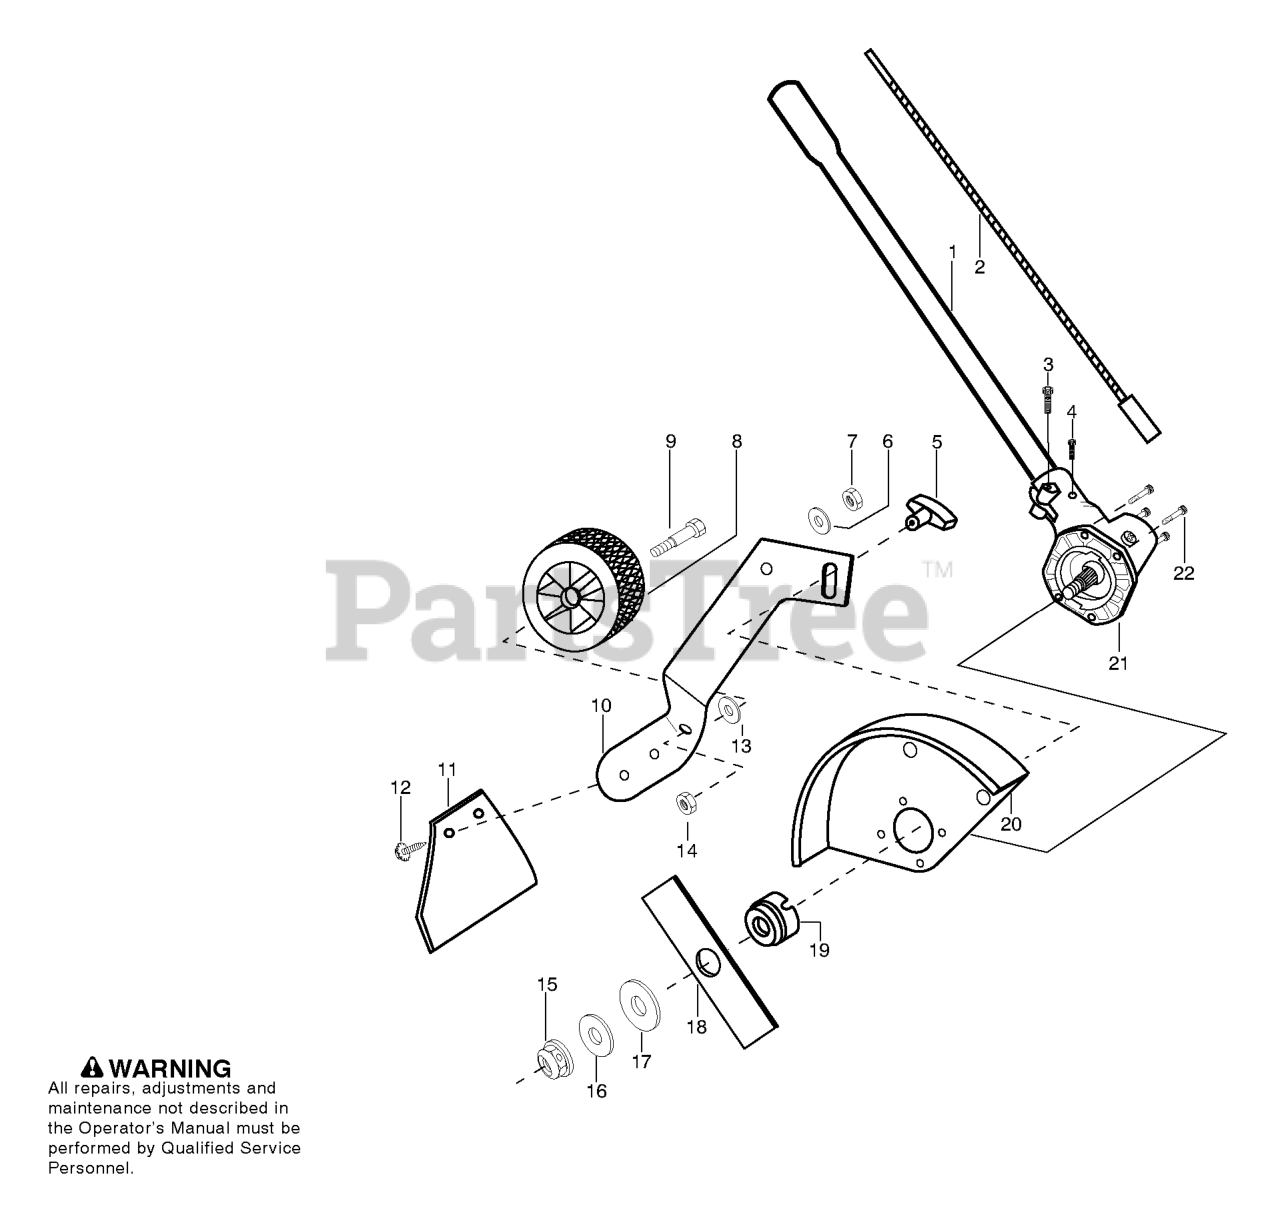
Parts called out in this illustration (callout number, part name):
1	DRIVE SHAFT
2	FLEX-LOWER
3	SCREW - CARB. ADAPTOR
4	SCREW 8-16 X 9/16 (PLAS
8	WHEEL-4"(FRONT)(RUBBER)
9	BOLT-SHOULDER AXLE
10	WHEEL BRKT ADJ
11	KIT MUD FLAP
12	FASTENER MUD FLAP
15	NUT-FLANGE (LH)
16	WASHER BELLVILLE
17	WASHER-FLAT.
20	KIT - EDGER GUARD
21	KIT GEARBOX EDGER HUSQ
22	SCR 10-24 MS LDK PAN PH
